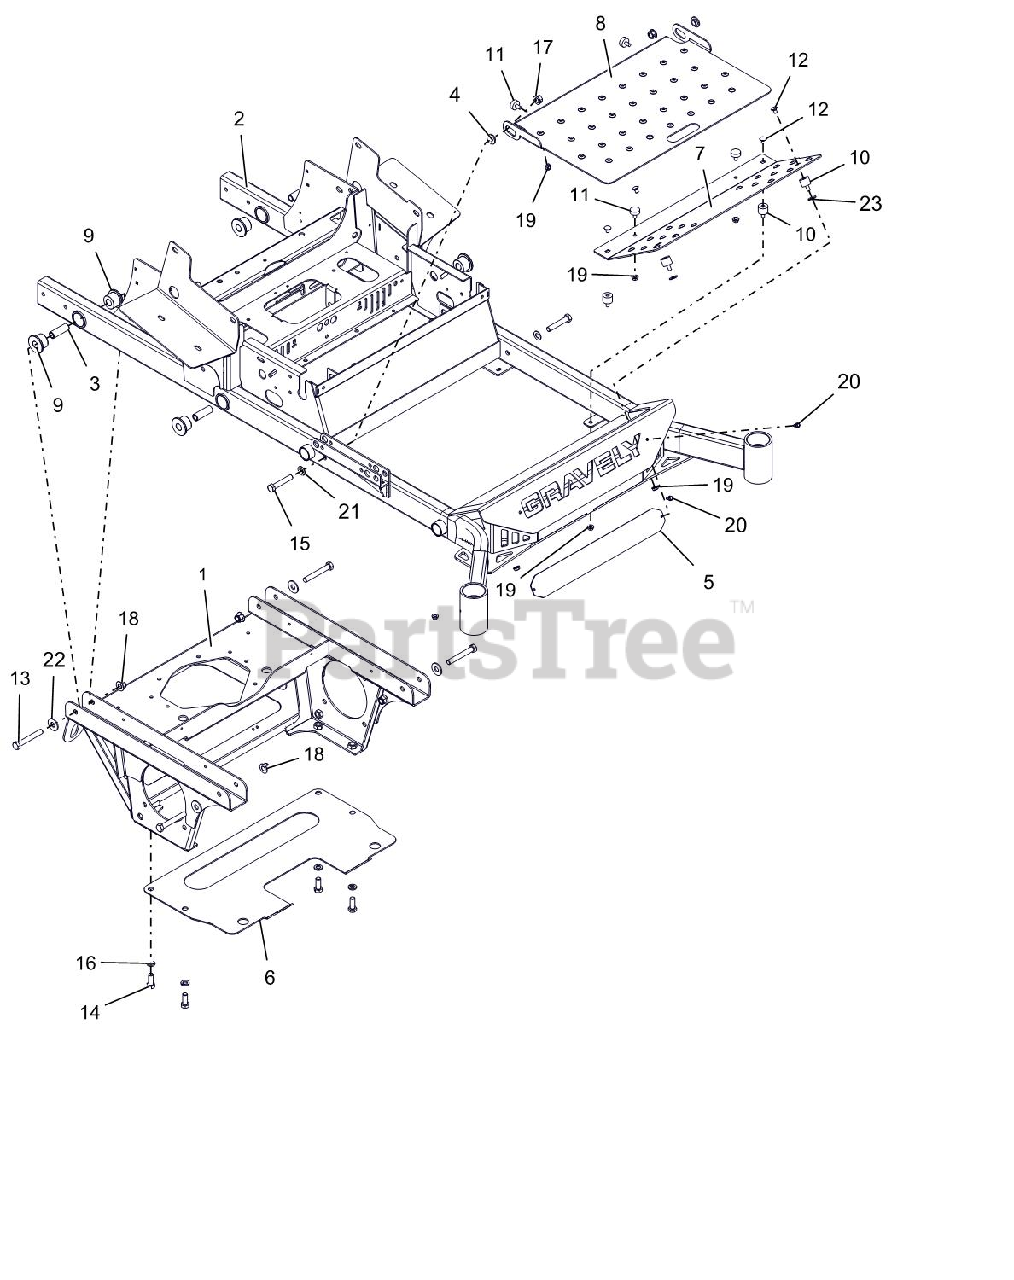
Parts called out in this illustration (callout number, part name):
1	PT200/400 AXLE/ENG FRM WMT-RED
2	52-60"PT200/400 FRAME W/DECALS
3	BSHG-SLV .50X.75X2.23
4	BSHG-FLG .515X.750X.310X1.120
5	BUMPER LOGO BACKING PLATE -BLK
6	PLATE-TRANSMISSION SKID
7	FOOTREST W/ SAFTEY DECALS
8	INSPECTION PANEL W/SAFE DECAL
9	BSHG-FLG .75X1.51X1.13X2.0 URE
10	BUMPER,STUD MNTD W/FEMALE INSR
11	BUMPER, RUBBER
12	@BLT-RDHDSQNK .31-18X.50 G5YZ
13	@BLT-HEX .50-13X3.50 GR5 YWZC
14	@BLT-HEX .50-13X1.25 GR5 YWZC
15	@BLT-HEX .50-13X2.75 GR5 YWZC
16	@WSHR-LK .50X.125 REG YWZC
17	NUT-LK-CTR-FLG .50-13 YWZC
18	@NUT-LK-NYL-FLG .50-13 YWZC
19	@NUT-SPNLK-FLG .312-18 YWZC
20	SCR-TAP .25-20X.50 HWH TR YWZ
21	WSHR-FL-STL.531X1.00X.063 YWZC
22	@WSHR-FL-STL.563X1.38X.109YWZC
23	@WSHR-FL-STL.38X.875X.083 YWZC
